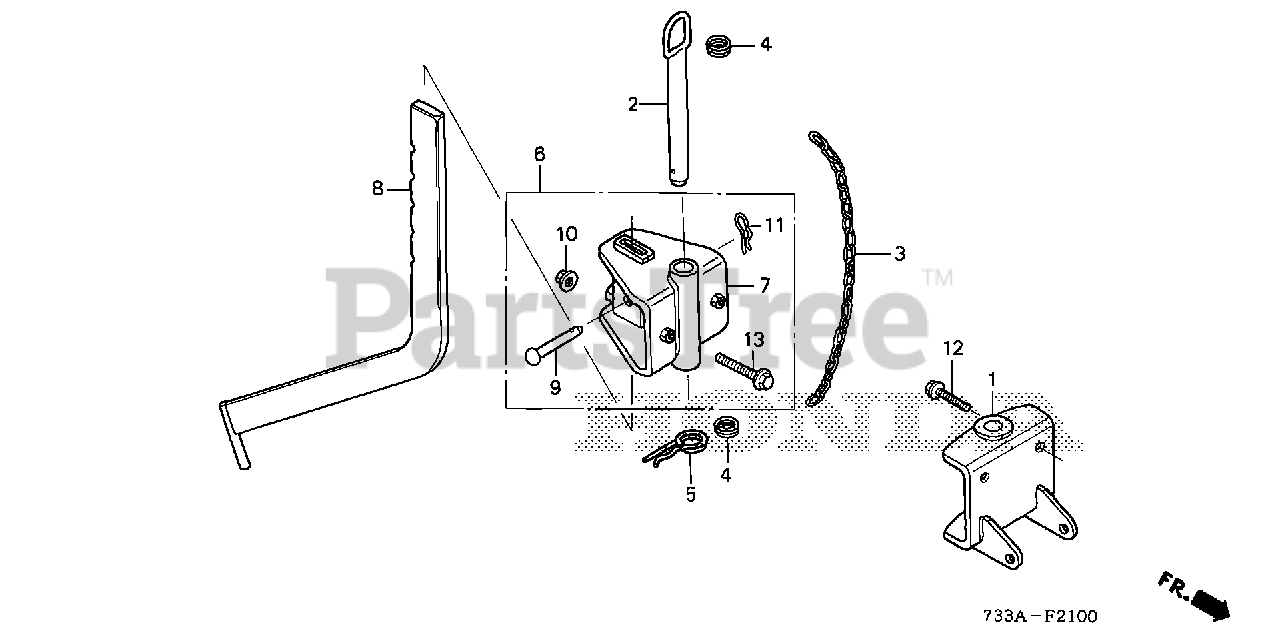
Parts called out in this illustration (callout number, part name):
1	BOX, HITCH
2	PIN, HITCH
3	CHAIN, CONNECTING
4	RING, CONNECTING (NOT AVAILABLE)
5	PIN, LOCK
6	HITCH ASSY., ATTACHMENT
7	HITCH, ATTACHMENT
9	PIN (10X53.5)
10	NUT, FLANGE (8MM)
11	PIN, LOCK (10MM)
12	BOLT, FLANGE (8X25)
13	BOLT, FLANGE (8X32)
